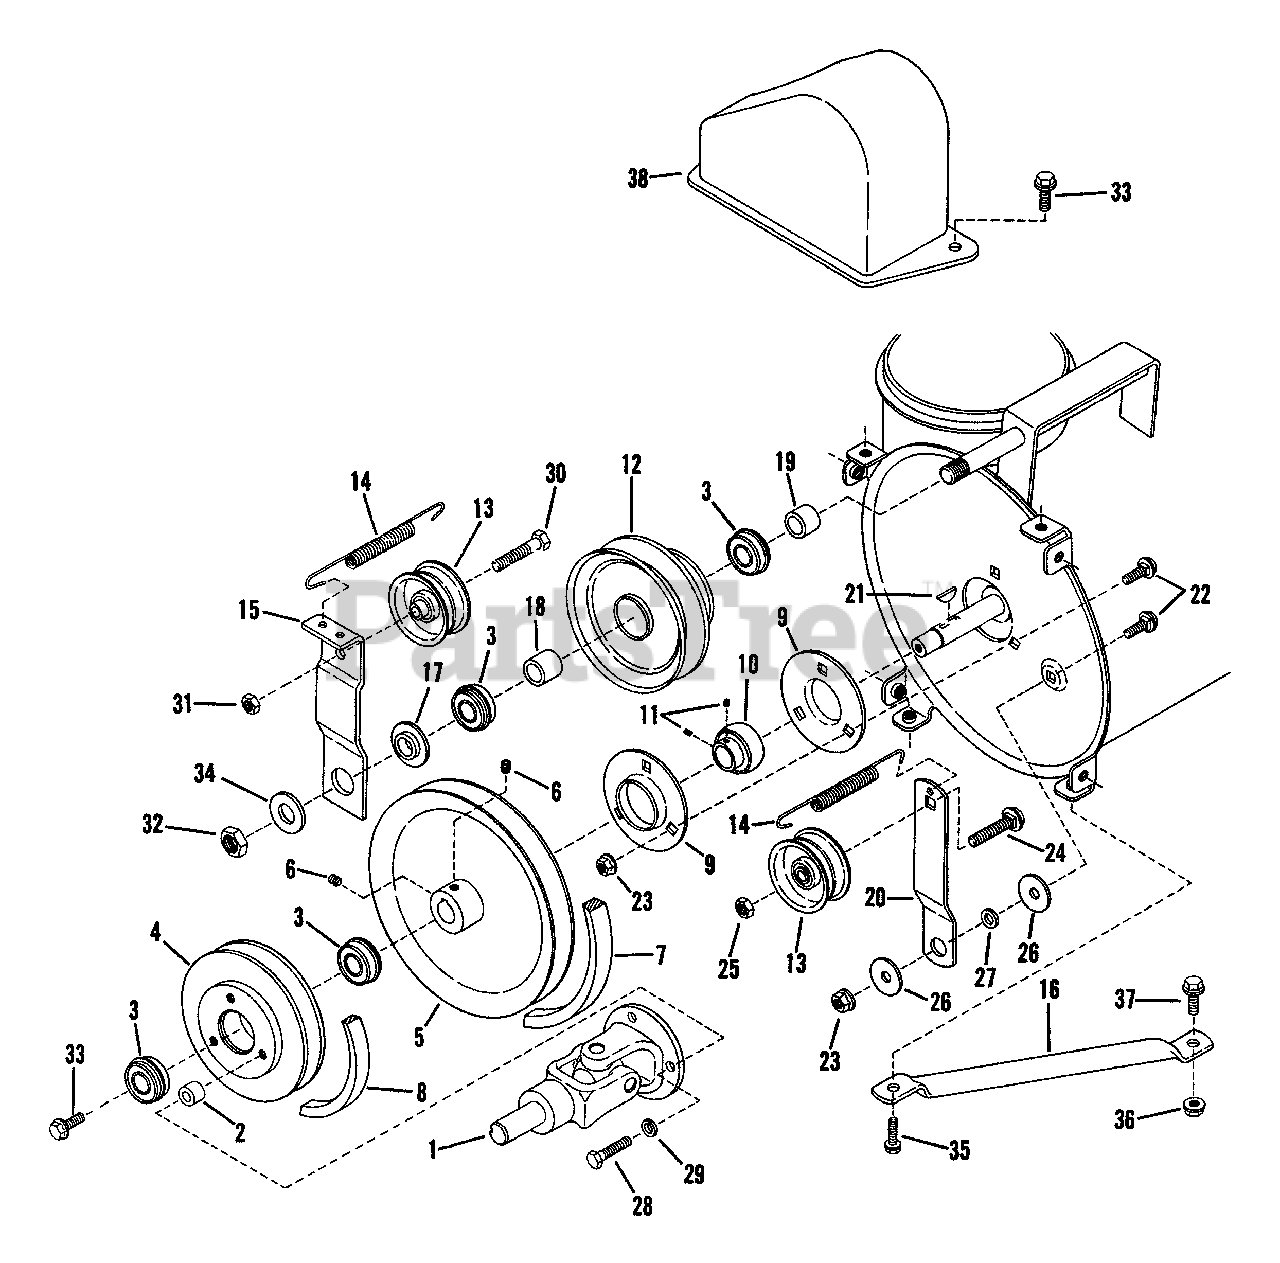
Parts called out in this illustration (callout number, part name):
1	SHAFT, Drive
3	BEARING
4	PULLEY, 5.25" O.D. (iron)
5	PULLEY, 8.36" O.D.
6	SCREW, 5/16 Socket Head Set
7	V-BELT
8	V-BELT
9	HOUSING, Bearing
10	BEARING
11	SCREW, #10-32 Socket Head Set
12	SHEAVE, Reduction
13	IDLER, 2.47" O.D.
14	SPRING, Idler
15	ARM, idler
16	BRACE
17	BUSHING
20	ARM, Idler
21	KEY, 3/16 x 7/8" Woodruff
22	BOLT, 5/16-18x3/4" Short Neck Carriage
23	NUT, 5/16-18 Hex Flange Lock
24	BOLT, 3/8-16x1-1/2" Carriage
25	NUT, 3/8-16 Hex Lock
26	WASHER, 5/16" x 1-1/4" x 3/32" Flat
27	SPACER
28	SCREW, 5/16-24x1" Hex Head Cap
29	WASHER, 5/16 Split Lock
30	SCREW, 3/8-16x1-1/2" Hex Head Cap
31	NUT, 3/8-16 Hex
32	NUT, 5/8-18 Hex Lock
33	SCREW, 5/16-18x5/8" Hex Thread Forming
34	WASHER, 5/8 Flat
35	SCREW, 1/4-20x3/4" Hex Thread Forming
36	NUT 1/4-20 Hex Flange Lock
37	SCREW 1/4-20x3/4" Hex Head Cap
38	COVER, Belt
